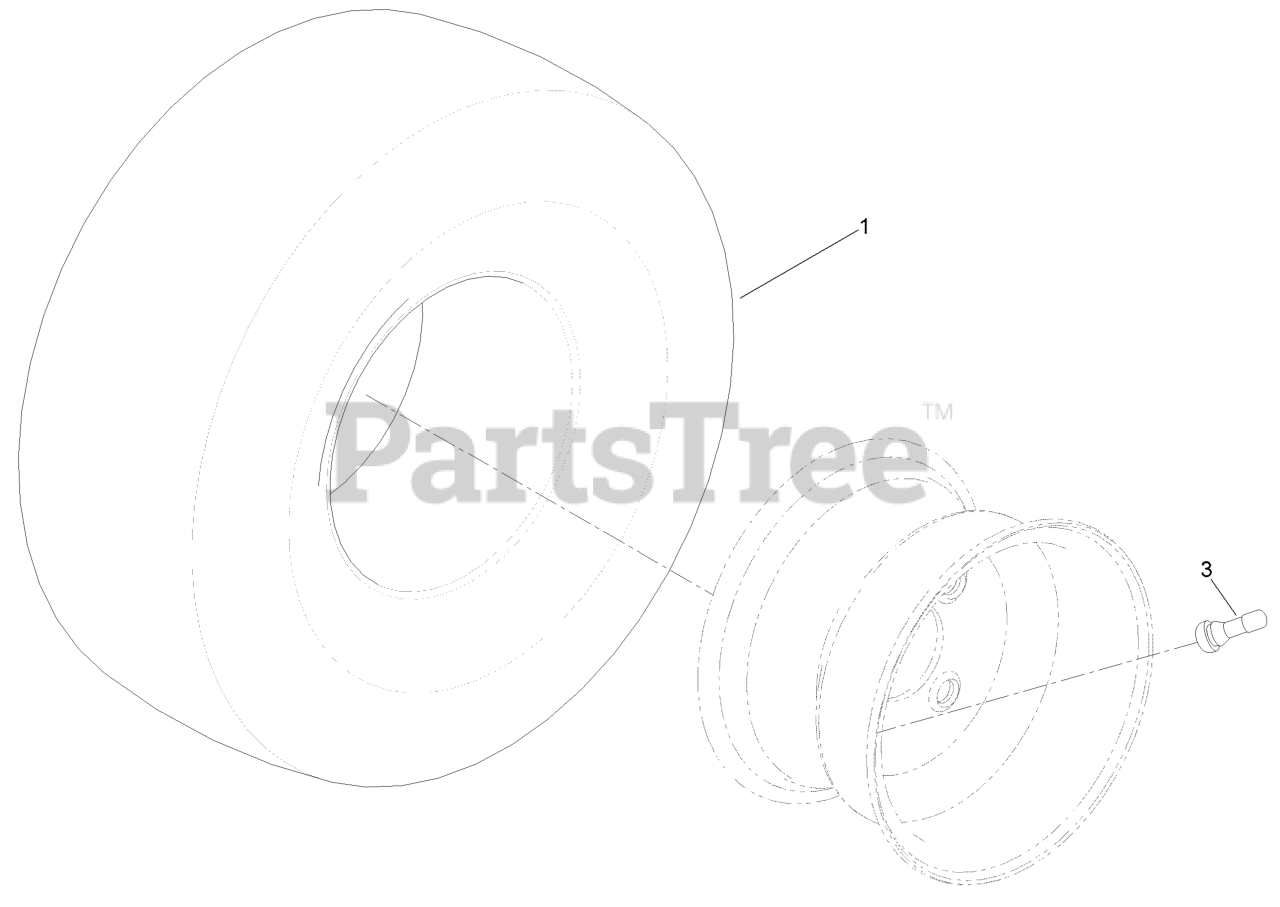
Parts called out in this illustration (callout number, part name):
1	TIRE-2 PLY
3	Stem-Valve
99	TUBE-TIRE
